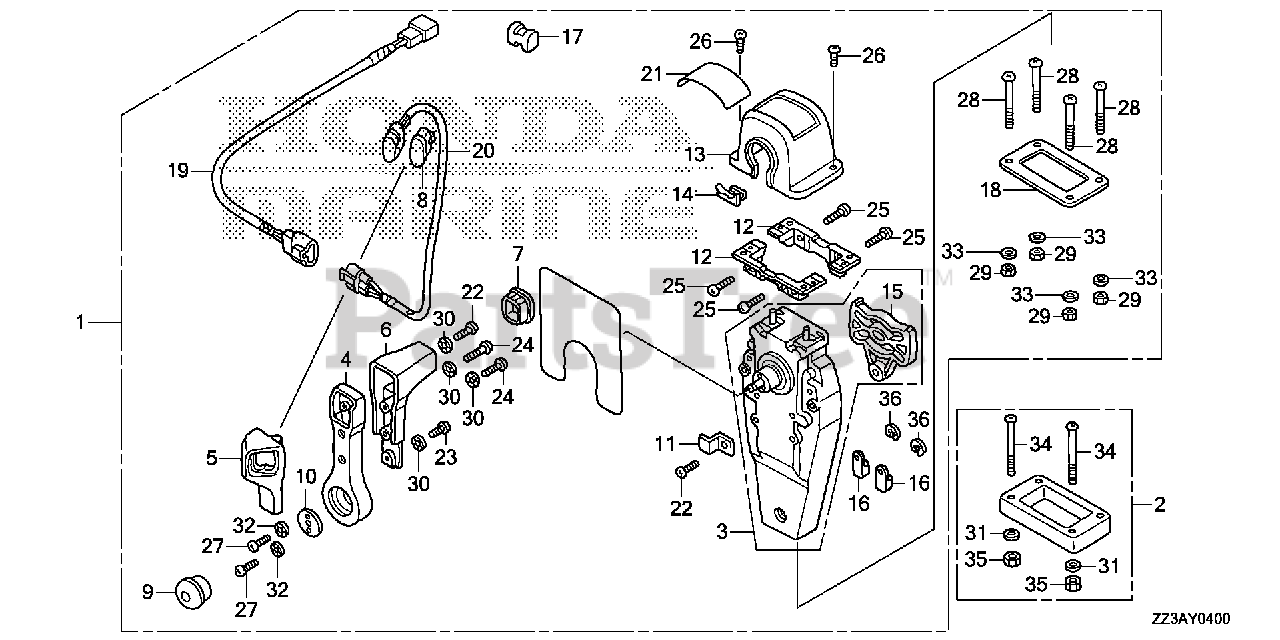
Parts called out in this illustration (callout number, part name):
1	BOX KIT, REMOTE CONTROL (TOP MOUNT SINGLE)(R)
2	SPACER KIT, REMOTE CONTROL BOX (TOP MOUNT SINGLE)
3	HOUSING ASSY., L. (INNER) (TOP MOUNT)
4	HANDLE, REMOTE CONTROL
5	COVER, L. GRIP
6	GRIP, REMOTE CONTROL HANDLE
7	CAP, GRIP
8	CAP, SWITCH
9	BUTTON, THROTTLE
10	PLATE, HANDLE
11	PLATE, CABLE CLAMP
12	BRACKET, REMOTE CONTROL HOUSING
13	HOUSING, REMOTE CONTROL BOX
14	HOUSING, LEAD
15	PLATE, DWELL
16	TERMINAL, CABLE
17	SPACER, CABLE CLAMP
18	GASKET, SINGLE
19	SUB-HARNESS ASSY., POWER TRIM-TILT (A)
20	SWITCH ASSY., POWER TRIM-TILT (A)
21	MARK, REMOTE CONTROL (SINGLE)
22	SCREW, PAN (5X16)
23	SCREW, PAN (5X10)
24	SCREW, PAN (5X20)
25	SCREW, PAN (5X18)
26	SCREW, PAN (4X10)
27	SCREW, PAN (6X18)
28	SCREW, PAN (5X40)
29	NUT, HEX. (5MM)
30	WASHER, LOCK (5MM)
31	WASHER, PLAIN (5MM)
32	WASHER, LOCK (6MM)
33	WASHER, PLAIN (5MM)
34	SCREW, PAN (5X65)
35	NUT, HEX. (5MM)
36	E-RING (6MM)
